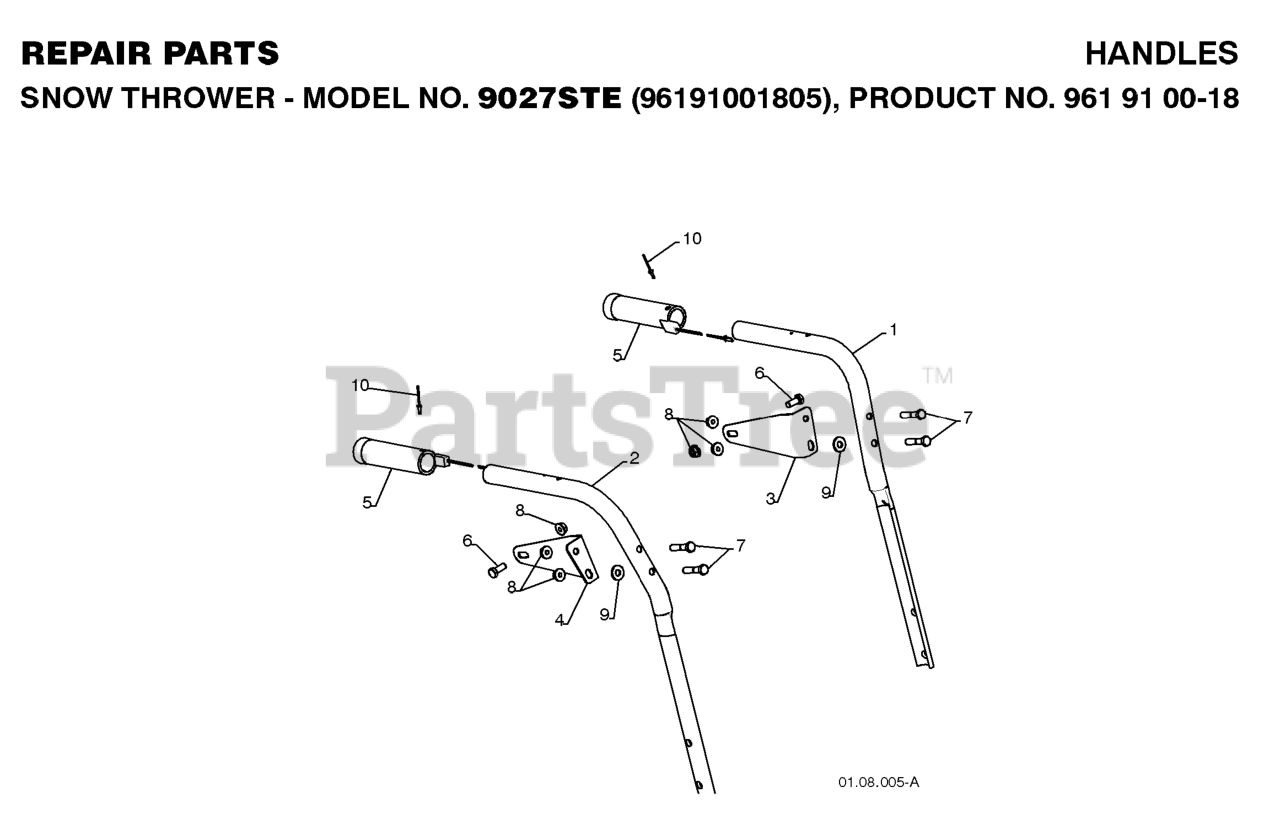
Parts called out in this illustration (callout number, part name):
1	TUBE.HANDLE.PLOW.LH.BLACK
2	TUBE.HANDLE.PLOW.RH.BLACK
3	BRKT.PANEL.LH.INT
4	BRKT.PANEL.RH.INT
5	GRIP.HANDLE.HEATED
6	BOLT.FIN.HEX.5/16-18X3/4
7	HEX BOLT
8	NUT.LOCK.5/16-18
9	WASHER.20X8.5
10	RIVET.POP.1/8X
